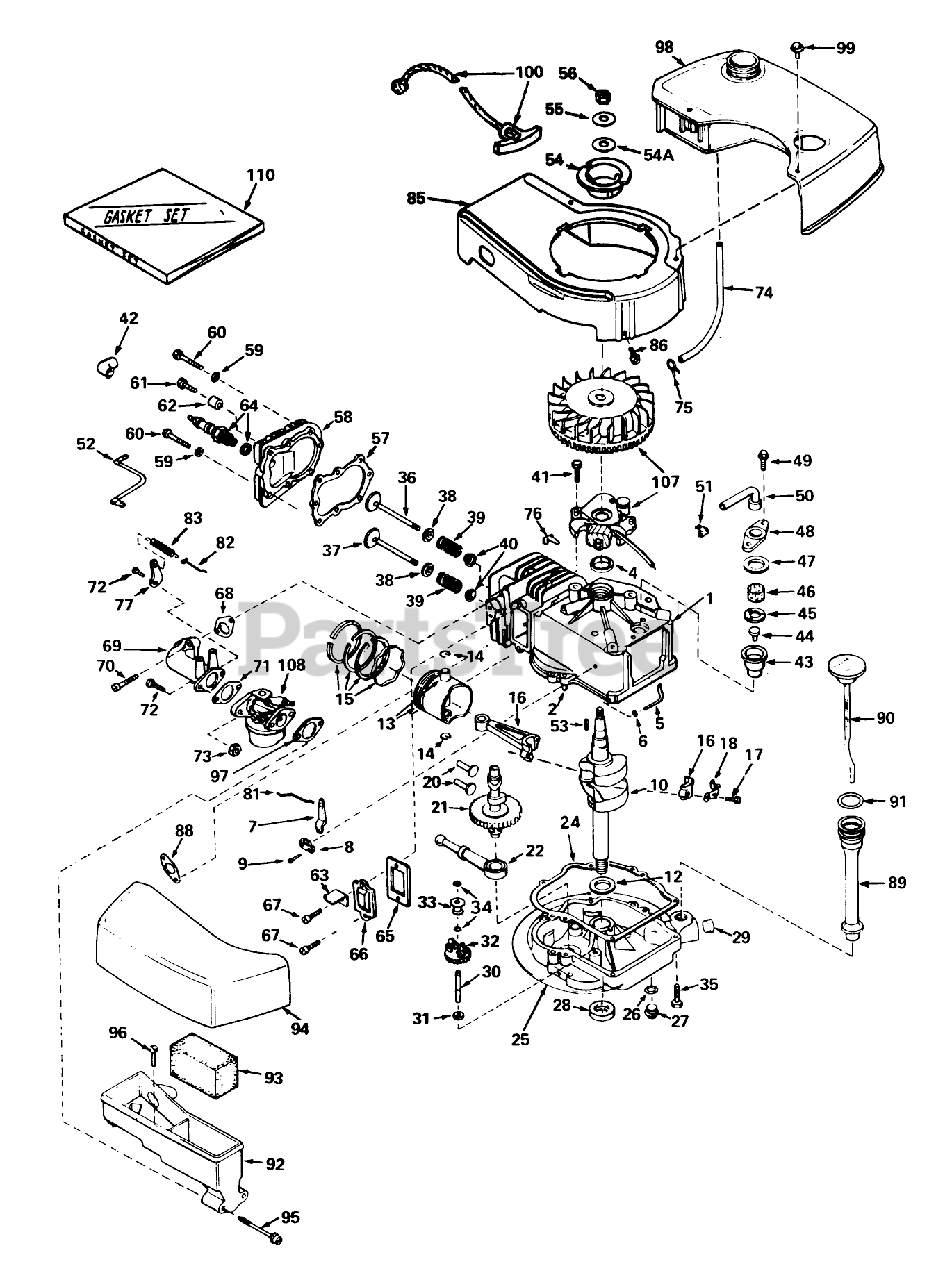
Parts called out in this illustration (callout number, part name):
1	Cylinder Assembly (Incl. Nos. 2, 4 87)
2	Pin-Dowel
4	Seal-Oil
5	Rod, Governor (Incl. No. 36)
6	Washer-Flat
7	Governor Lever
8	Clamp-Lever, Governor
9	Screw
10	Crankshaft
12	Washer-Thrust
13	Piston Pin Assembly (Incl. 2 of No. 14)(Std.)
13	Piston Pin Assembly (Incl. 2 of No. 14)(.010 Oversize)
13	Piston Pin Assembly (Incl. 2 of No. 14)(.020 Oversize)
14	Ring-Retaining, Piston Pin
15	Ring Set-Piston Std.
15	Ring Set-Piston .010 oversize
15	Ring Set-Piston .020 oversize
16	Rod Assembly, Connecting (Incl. Nos. 17 18)
17	Connecting Rod Bolt
18	Plate Lock
20	Lifter-Valve
21	Camshaft(Mech.Comp. Release)
22	Oil Pump ASM
24	Gasket, Mounting
25	Flange Assembly, Mounting (Incl. #27, 28, 29 30)
26	Gasket-Oil Drain
27	Plug Oil Drain
28	Seal-Oil
29	Plug Oil Drain
30	Shaft-Governor
31	Washer-Flat
32	Gear Assembly, Governor
33	Spool, Governor
34	Ring-Retaining
35	Screw (1/4-20 x 1-1/4)
36	Valve, Intake (Incl. Ref. #38, 39 40) (Std.)
36	Valve, Exhaust (1/32" Oversize) (Incl. Nos. 8, 9 10)
37	Valve, Exhaust (Standard) (Incl. Nos. 8, 9 10)
37	Valve, Exhaust (1/32" Oversize) (Incl. Nos. 8, 9 10)
38	Cap-Upper Valve Spring
39	Spring-Valve
40	Cap-Valve, Spring
41	Screw
42	Cover-Spark Plug
43	Body Breather Tube
44	Valve Check
45	2000A37 WIZARD ROTA
46	Element-Breather
47	Gasket-Breather
48	Cover Breather
49	Screw, Hex Hd. w/Conical
50	Tube, Breaker
51	Clip, Breather
52	Wire, Ground
53	Key Flywheel
54	Pulley Starter
54A	Washer Flat
55	Washer, Belleville
56	Nut, Flywheel
57	Oil Fill Tube
58	Head Cylinder
59	Washer
60	Screw
61	Screw Hex Hd. Cap
62	Space
63	Retainer Clip
64	Plug, Spark (J17LM or equiv.)
65	Gasket-Breather
66	Cover-Valve
67	Screw
68	Gasket, Intake
69	Pipe, Intake
70	Screw (1/4-20 x 1)
71	Gasket-Carburetor
73	Nut and Lock Washer (1/4-28)
74	Line-Fuel
75	Clamp-Line, Fuel
76	Clip-Wire
77	Lever-Adjusting, R P M
81	Link Governor
82	Link Governor Spring
83	Spring Governor
85	53024/VAR.GT O/P W/
86	Screw
88	Gasket Exhaust
89	Tube, Oil Filler
90	Dipstick, OiI (Incl. No. 91)
91	O-Ring
92	Body Air Cleaner
93	Filer, Air
94	Cove, Air Cleaner
95	Screw Fil Hd.
96	Screw, Hex Hd.
97	Gasket-Air Cleaner
98	Tank Fuel
99	Screw (10-32 x 35/64)
100	Rope Assy., Starter
107	Magneto
108	Carburetor
110	53024/VAR.16HP O/P
